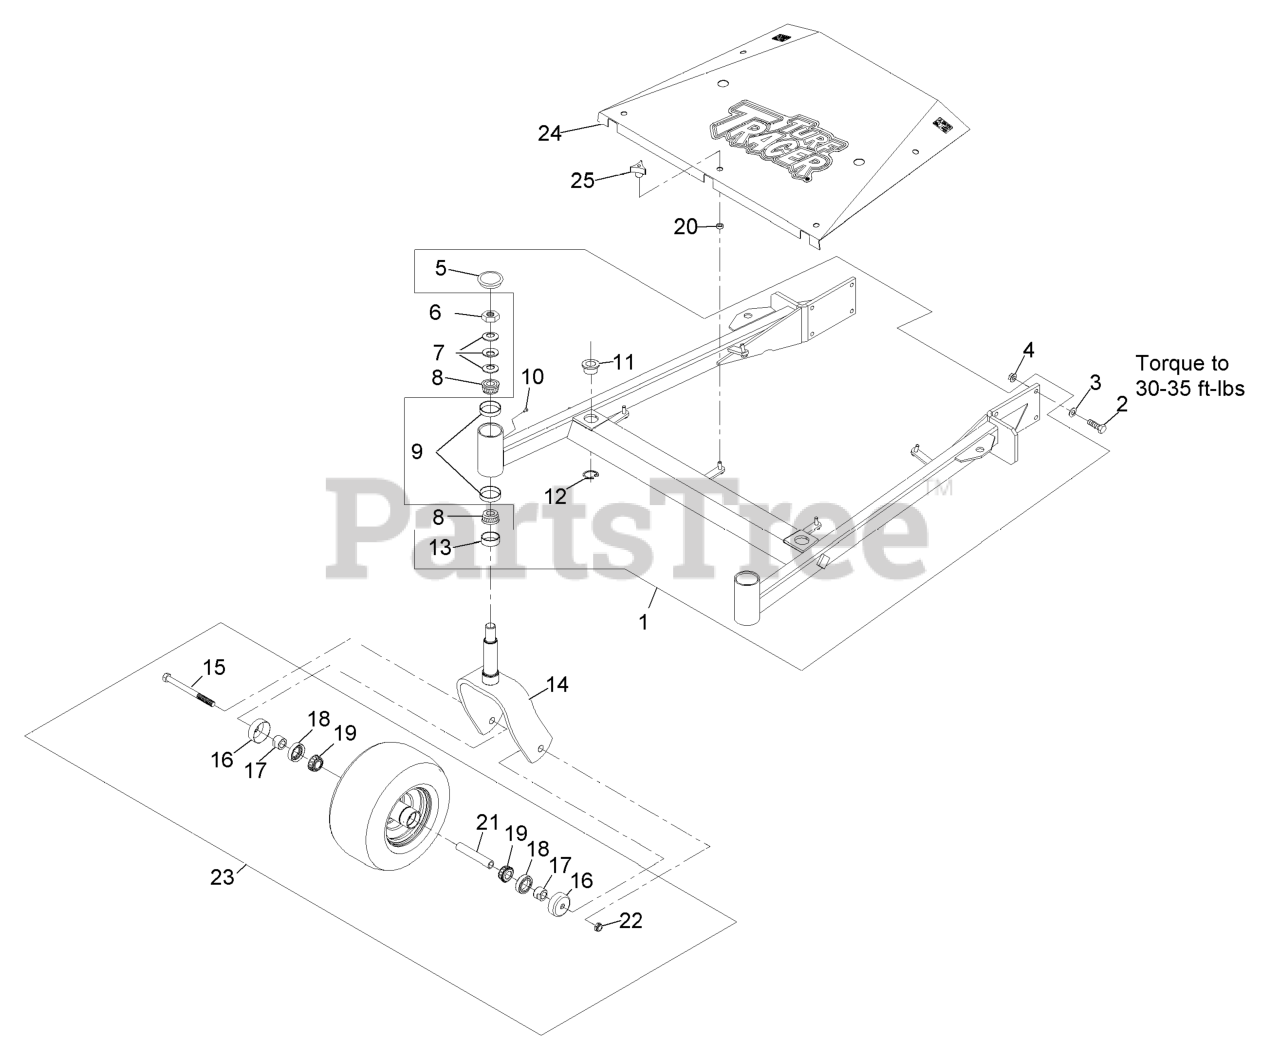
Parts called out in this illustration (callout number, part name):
1	ASM,FMD604 DK SUPPORT, SE
2	SCREW-HH
3	WASHER-BELLEVILLE
4	NUT-HHF, WHIZ
5	CAP-GREASE
6	NUT-LOCK, NI
7	WASHER-BELLVILLE
8	Cone-Bearing Tapered Roller
9	CUP-BEARING
11	BUSHING-DECK
12	RING-RETAINING
13	SEAL-GREASE
14	WLD, CASTER FORK
15	SCREW-HH
16	GUARD-SEAL
17	SPACER-NUT
18	SEAL-CASTER
19	BEARING-CONE, TAPERED ROLLER
22	NUT-HEX
23	ASM,WHEEL&BEARINGS
24	KIT,SHIELD TT604 W/ DECAL
25	KNOB-3 PRONG
